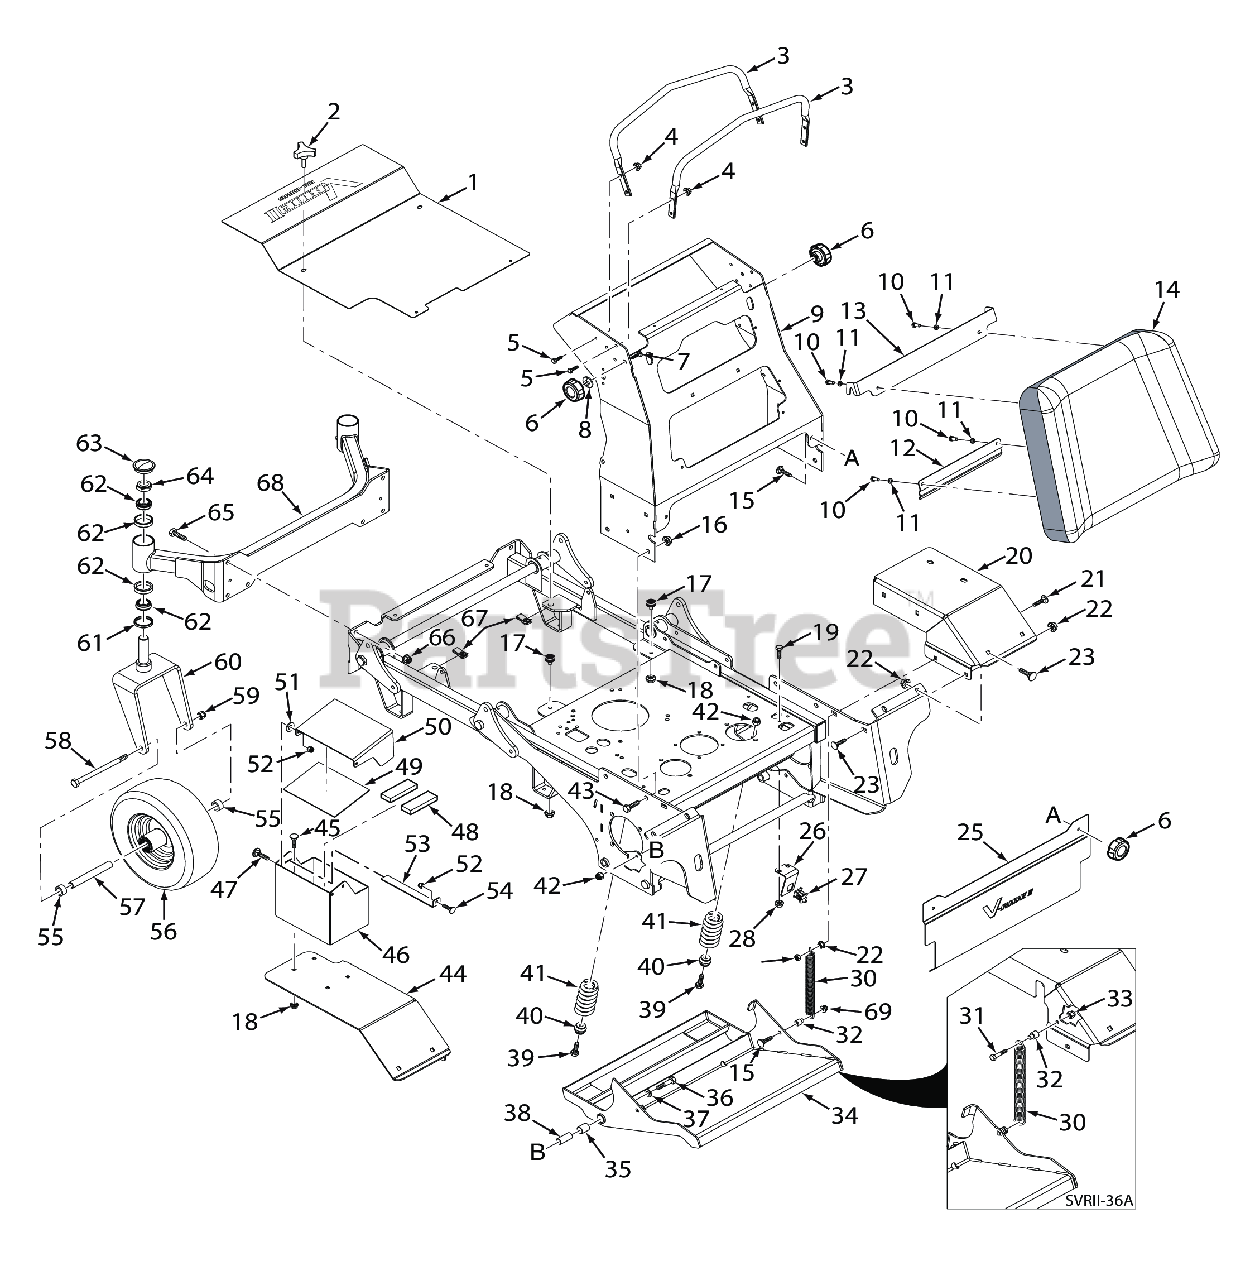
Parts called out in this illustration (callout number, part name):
1	Belt Cover w/Decals
2	Knob, w/stud 3/8-16 x 1-1/4"
3	Reference Bar
4	Nut, Serrated Flange 5/16-18 (Right Front Engine Mounting, Briggs and Kohler Only)
5	BOLT, SERRATED FLANGE HEX HEAD 5/16-18 X 3/4"
6	Knob, 5/16-18
7	Bolt, Carriage 5/16-18x1" (large frame units only)
8	Nut, Push-On 5/16-18
9	Handlebar Weldment, SVRII
10	BOLT, SERRATED FLANGE HEX HEAD 5/16-18 X 3/4"
11	Lockwasher, 5/16 (.317 x .586 x .078) Helical Spring
12	Bracket, Knee Pad - Lower
13	Bracket, Knee Pad - Upper
14	Operator Pad Assy, SVRII
15	Bolt, 5/16-18 x .75 RHSN Carriage
16	Locknut, 1/2-13 Spiral Lock
17	Bumper, Rubber 5/16-18 x 5/8"
18	Nut, Serrated Flange 5/16-18 (Right Front Engine Mounting, Briggs and Kohler Only)
19	BOLT, HEX HEAD, 1/4-20 X 3/4 GR.5
20	Fender, RH
21	Bolt, RDHD Carr. 3/8-16 x 1-1/2 (52" & 61")
22	NUT, 3/8-16 SERRATED FLANGE HEX HEAD
23	Bolt, Carriage 3/8-16 x 3/4"
24	Mainframe Assy. - SVRII
25	Guard, Foot -SVRII
26	Switch Bracket, Operator Presence
27	SWITCH, NEUTRAL INTERLOCK
28	NUT, 1/4-20 SERRATED FLANGE HEX HEAD
29	Nut, Flange Elastic Stop Nut, 3/8-16
30	Spring,Counter Balance
31	Bolt, Hex Head 5/16-18 x 1-1/2" (Right Front Engine Mounting, Briggs and Kohler Only)
32	Spacer, Pump Dampener
33	HEX NUT, ELASTIC STOP LOCK, 5/16-18
34	Footplate Assy, SVRII
35	Bearing, .750 I.D. Plastic
36	Capscrew, Hex Head 3/8-16 x 2.0"
37	Flatwasher, 3/8" Special (.391 x .938 x .105)
38	Yoke, Front Caster Wheel
39	Bolt, Hex Head 3/8-16 x 1-3/4" (Kohler EFI)
40	Mount, Spring
41	Spring, Suspension Platform
42	HEX NUT, ELASTIC STOP LOCK, 3/8-16
43	Capscrew, 1/2-13 x 1" Serrated Flange Hex Head
44	Fender, LH
45	Bolt, 5/16-18 x .75 RHSN Carriage
46	Battery Box, Lower
47	Bolt, Carriage 1/4-20 x 1/2"
48	PAD, BATTERY SUPPORT
49	Insulation, Battery Cover (Gas Only)
50	Battery Box, Upper
51	Flatwasher, 1/4" (.312 x .750 x .065")
52	HEX, NUT, ELASTIC STOP LOCK, 1/4-20
53	Battery Box Latch
54	Bolt, Carriage 1/4-20 x 1/2"
55	Spacer, Caster Wheel
56	Wheel Assy, 52V (Incl. items 20, 54, 55)
57	Sleeve, Caster Wheel (52V)
57	Sleeve, Caster Wheel (48 / 52)
58	Bolt, Hex Head 1/2-13 x 7-1/2" (48"/52")
59	HEX LOCKNUT, ELASTIC STOP, 1/2-13
60	Yoke, Front Caster Wheel (48"/52")
61	Seal, 2.00" O.D. x 1.625" Bore
62	BEARING & CUP, TAPERED SPINDLE
63	Cap, Grease
64	Nut, Hex Elastic Stop 1.0"-14
65	BOLT, HEX HEAD, 7/16-14 X 1-1/4
66	Nut, 7/16-14 Flange Elastic Stop
67	U-Nut, 3/8-16
68	Caster Support Weldment (52)
69	Nut, Flange Head Elastic Stop 5/16-18
